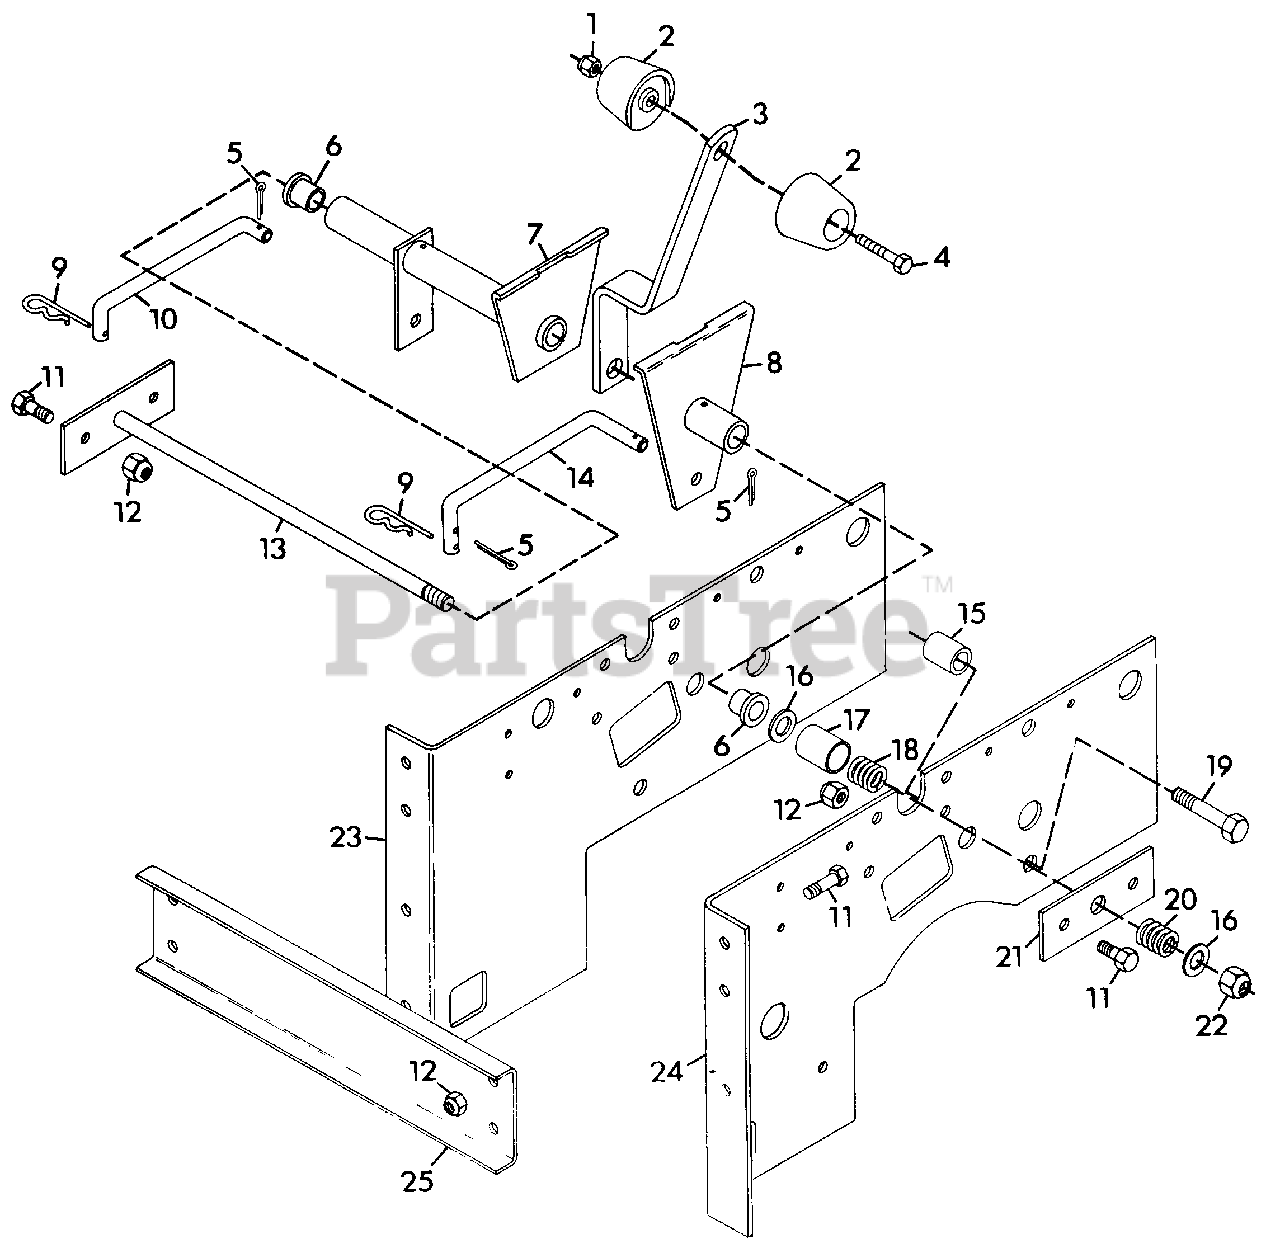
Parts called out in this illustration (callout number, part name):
1	NUT, LOCK 1/4-20
2	KNOB, CONTROL
3	LEVER, SHIFTER
4	BOLT, HEX 1/4-20X1.50
5	PIN, COTTER .09X.75
6	BUSHING, CABLE GUIDE PULLEY
7	WELDMENT, SHIFT LEVER L.H.
8	WELDMENT, SHIFT LEVER R.H.
9	PIN, COTTER HAIR
10	ROD, GEAR SHIFT
11	BOLT, HEX 3/8-16X.875
12	NUT, LOCK 3/8-16
13	WELDMENT, CROSS SHAFT
14	ROD, GEAR SHIFT
15	BUSHING, .505X.750X1.00
16	WASHER, FLAT .531X1.062X.095
17	SPACER, #2 SHAFT
18	SPRING, COMP. 2.75X.625X34 RATE
19	BOLT, HEX 1/2-13X2.00
20	SPRING, COMP. 1.00X.78X338 LB/IN
21	PLATE, CROSS SHAFT(4-SP)
22	NUT, LOCK 1/2-13
23	BRACKET, CONTROL MOUNT R.H.
24	BRACKET, CONTROL MOUNT L.H.
25	BRACKET, HYDRAULIC TANK
